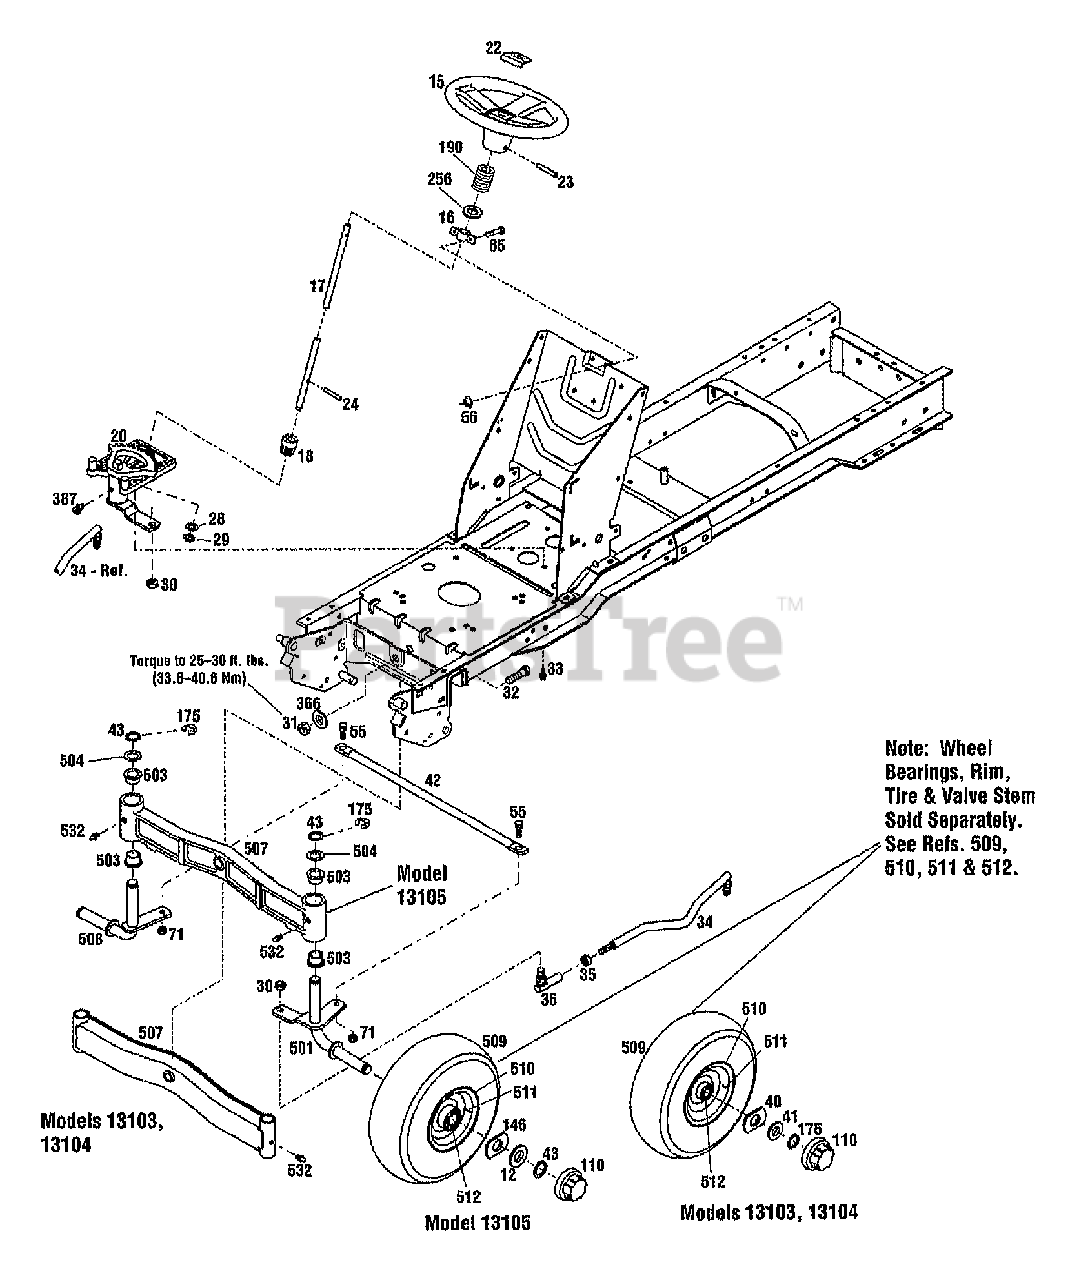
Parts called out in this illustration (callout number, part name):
15	WHEEL-STEERING
16	BEARING
17	SHAFT-STEERING
18	GEAR-PINION
20	ASSM-STEERING GEAR
22	CAP-STEERING
23	PIN-ROLL .25X2.25
24	PIN-ROLL 1/4 X 1-1/4
28	WASHER-1.0X.64X.09
29	RING-RETAINING
30	NUT-HEX/JAM 1/2-20
31	NUT-H/LK 5/8-11
32	SCR-HH
33	SCR-HFLK 5/16-18X.75
34	LINK-DRAG
35	NUT-JAM
36	JOINT-BALL
40	WASHER-SPEC .75X2.50 {13103,13104}
41	WASHER-1.38 X.765X .06 ZP {13103,13104}
43	RING-HEAVY EXT HD 1.0 ID {13105}
55	SCR-SHOULDER
56	NUT-HF/LK 1/4-20 ZP
65	SCR-HH 1/4-20X.625
71	NUT-LOCK
110	CAP-HUB
146	WASHER-SPECIAL .75X2.5 {13105}
175	RING-RET."E".577 ID {13103,13104}
190	SPRING-COMPRESSION
256	WASHER-1.0X.64X.029
366	WASHER-1.75X.687X.134 ZP
387	FITTING-GREASE 90 DEGREE
501	ASSM-SPINDLE LH {13103,13104}
501	SPINDLE-WHEEL LH {13105}
503	BUSHING {13103,13104}
503	BEARING-FLANGE {13105}
504	WASHER-1.25X.765X.049 {13103,13104}
504	WASHER-THRUST {13105}
507	AXLE-FRONT {13103,13104}
507	AXLE-FRONT {13105}
508	ASSM-SPINDLE WHEEL RH {13103,13104}
508	SPINDLE-WHEEL RH {13105}
509	TIRE 15X6.00-6RS {13103,13104}
509	TIRE-16X6.50-8 {13105}
510	DISC WHEEL {13103,13104}
510	RIM-WHEEL {13105}
511	STEM-VALVE
512	BEARING-BALL W/SEAL {13103,13104}
512	BEARING-BALL {13105}
532	FITTING-GREASE 1/4-28X2.00
